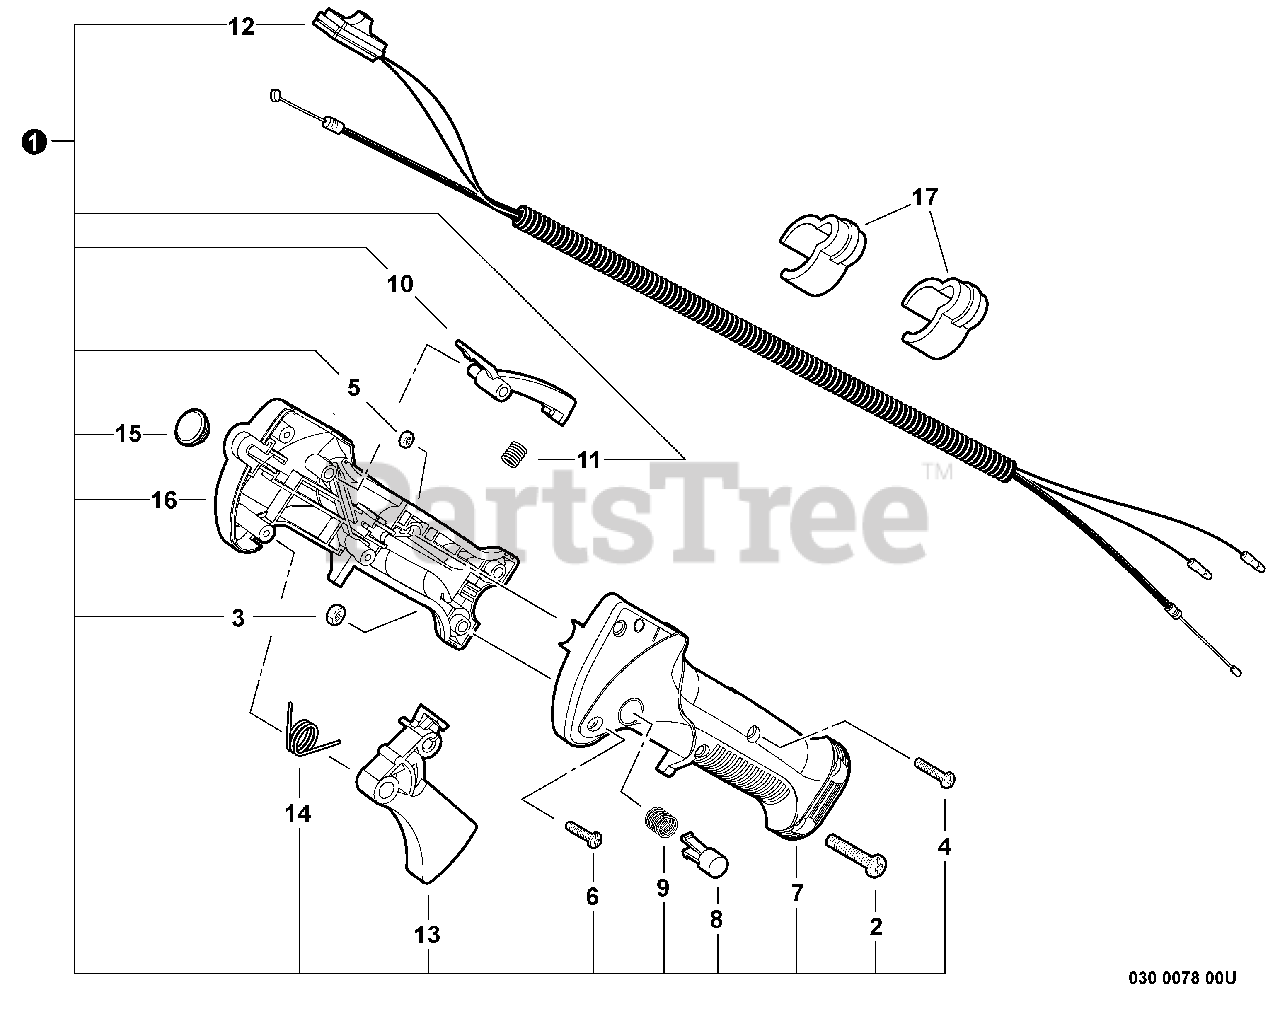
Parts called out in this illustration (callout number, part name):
1	CONTROL HANDLE KIT
2	SCREW - 5X20
3	NUT - 5
4	SCREW - 4X23
5	NUT - 4
6	SCREW - 4X16 -- TAPPING
7	HANDLE, CONTROL - LEFT
8	LOCK, THROTTLE
10	LEVER, TRIGGER LOCKOUT
12	CONTROL CABLE ASSY
13	TRIGGER, THROTTLE
14	SPRING, TRIGGER
16	HANDLE, CONTROL - RIGHT
